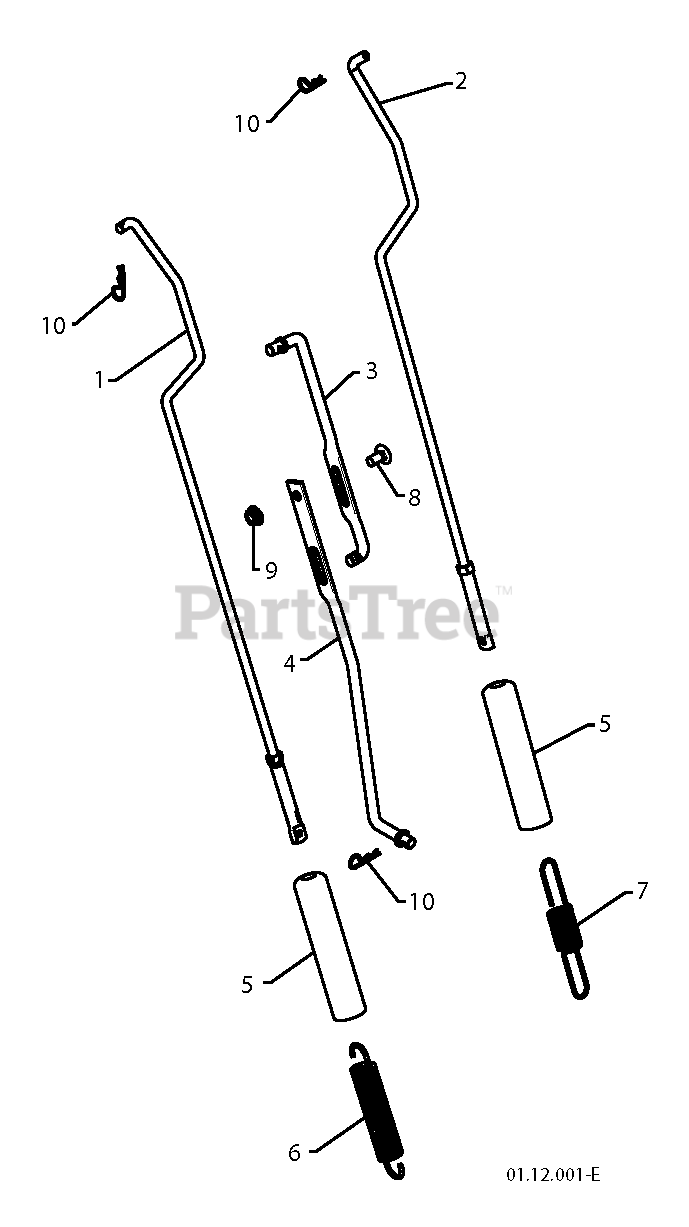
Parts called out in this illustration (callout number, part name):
1	ROD.ASM.IMPELLER
2	ROD.ASM.TRACTION
3	ROD, UPPER SPEED CONTROL
4	ROD, LOWER SPEED CONTROL
5	SLEEVE, SPRING
6	SPRING, AUGER CONTROL
7	SPRING, TRACTION DRIVE
8	BOLT
9	NUT.FLANGE.5/16
10	SPRING RETAINER
